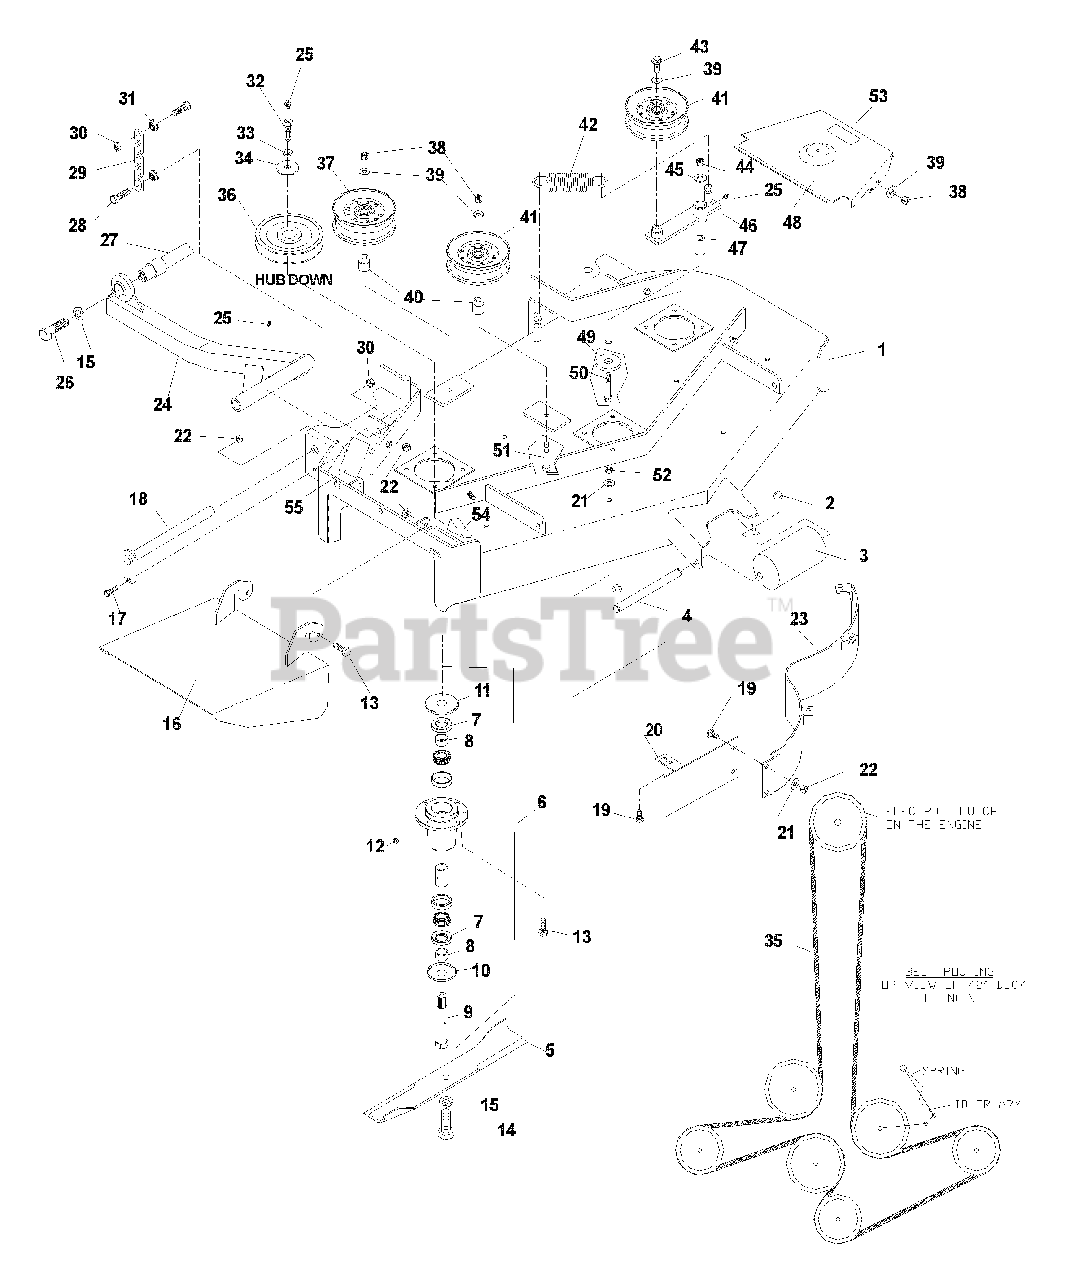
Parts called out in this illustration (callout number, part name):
1	DECK W/DECALS
2	1/2" E-RING
3	ROLLER, LONG
4	AXLE, ROLLER
5	BLADE 14 7/8"
6	CUTTER HOUSING, COMPLETE
7	SHAFT SEAL
9	MINI SPINDLE
10	DUST CAP, BOTTOM
11	DUST CAP, TOP
12	GREASE POPET
13	HCS 5/16C X 1 1/4
14	HCS 5/8F X 1 1/4
15	LOCKWASHER
16	DISCHARGE CHUTE
17	HCS 5/16C X 3/4
19	CARRIAGE BOLT 5/16 X 5/8
20	CENTER BAFFLE
21	WASHER 5/16C, NYLOC
22	NUT 5/16 CTR. LOCK
23	MAIN BAFFLE
24	STRUT - RIGHT
25	1/4-28 ZERK
26	HCS 5/16C X 2
27	STRUT MT. WLD.
28	HCS 7/16C X 1 1/2
30	7/16C CTR. LOCK
31	7/16C WHIZ NUT
32	HCS 7/16F X 1 1/2, SPEC.
33	7/16 LOCKWASHER
36	PULLEY
37	IDLER PULLEY 1.62
38	NUT 3/8C, NYLOC
39	WASHER 3/8 STD.
40	IDLER BUSHING
41	IDLER PULLEY 1.31
43	HCS 3/8C X 1
44	NUT 1/2C NYLOC
45	WASHER 1/2 STD.
47	PIVOT BUSHING
48	BELT SHIELD, LEFT
49	SUPPORT WASHER
50	HCS 1/2C X 3 1/4
51	HCS 3/8C X 2 3/4
53	DECAL, NO STEP
54	DECAL, CPSC
55	DECAL, DANGER
